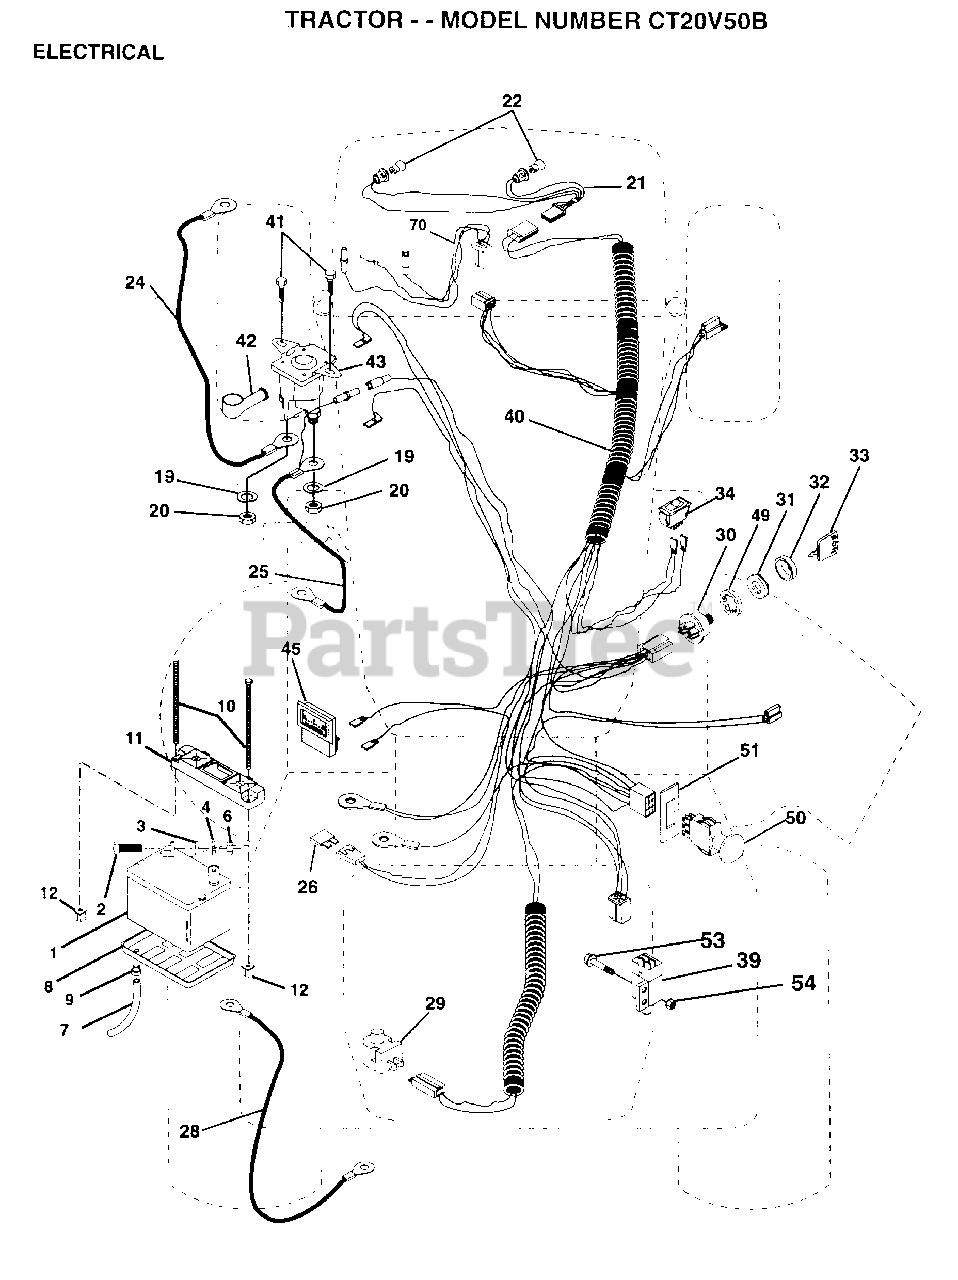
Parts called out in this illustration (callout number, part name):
2	BOLT LT
3	WASHER
4	LOCKWASHER
7	"DRAIN TU T, BATT"
8	"TRAY T, BATTERY"
9	HOSE CLAMP T
20	NUT
21	"HARNESS,LIGHT SOC"
22	HEADLAMP BULB
24	CABLE-BATTERY T
25	CABLE.6GA.12.5.
26	FUSE HYT
28	CABLE T
29	SWITCH SEAT
32	COVER KEY SWITCH
33	KEY MLD GEN DELTA
34	SWITCH LT
39	SWITCH INTERLOCKT
40	HARNESS.IGN.SRSGT
41	SCREW
45	AMMETER
49	LOCKWASHER
51	RING RETAIN PTO
53	SCREW
54	"NUT,KEPS"
70	HARNESS.ENG.VANII
